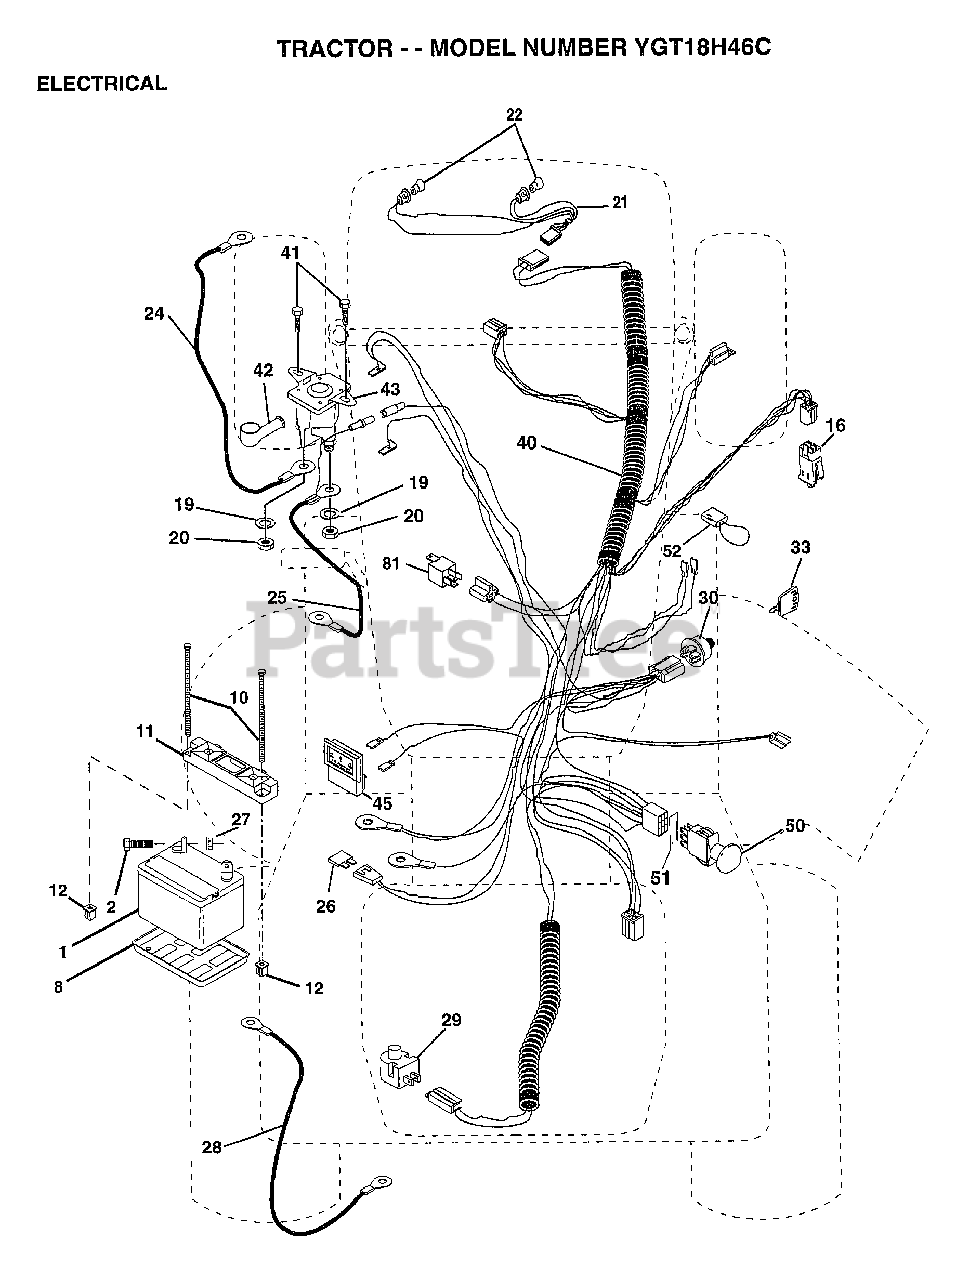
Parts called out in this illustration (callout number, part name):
2	BOLT LT
8	"TRAY T, BATTERY"
11	HOLDDOWN BATTERY
16	SWITCH INTERLOCK
20	NUT
21	HARNESS.ASM.LIGHT.W/4152J
22	HEADLAMP BULB
24	CABLE.BATY.22.RED
25	CABLE.BATRY.4GA.
26	FUSE HYT
27	NUT
28	"CABLE BATTERY,GRD"
29	SWITCH.PLUNGER
30	SWITCH.IGN.
33	KEY MLD GEN DELTA
40	HARNESS.IGNITION
41	SCREW
45	AMMETER
50	PTO SWITCH.BLK
51	RING RETAIN PTO
52	PROTECTION LOOP
81	RELAY ASSY T
